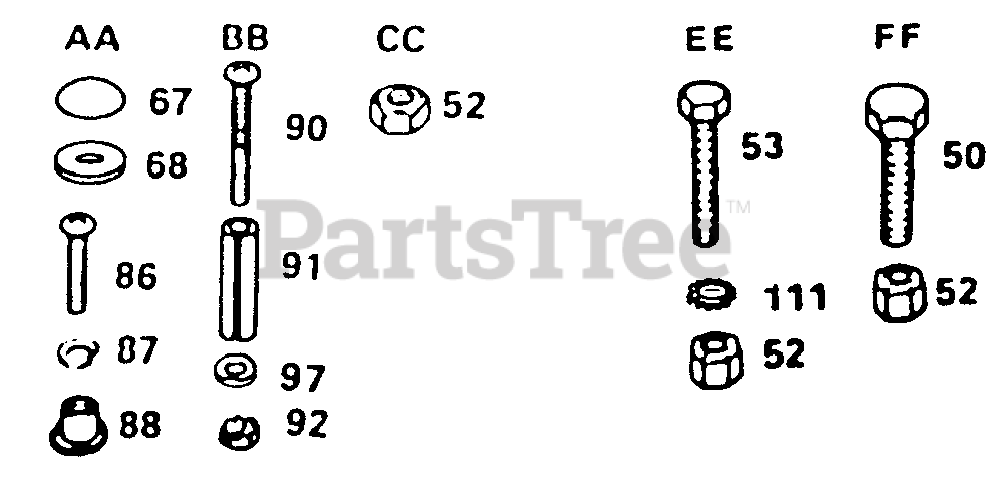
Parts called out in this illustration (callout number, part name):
50	Bolt, Hex 3/8 - 16 x 3/4
52	Nut, Crownlock 3/8 - 16
53	Bolt, Hex 3/8 - 16 x 1
67	Cap, Snap. Black
68	Washer, Cap, Snap
86	Screw, Cross Recess Pan Hd.Machine 10-24 x 1/2
87	Washer, Lock, No. 10
88	Nut, Weld
90	Screw, Machine Cross Recess 10 - 24 x 1-1 /4
91	Spacer, Split 10 x 3/4
92	Nut, Keps 10-24
97	Washer, 7/32 x 1/2 x 18 Ga.
111	Lockwasher, 3/8 Ext. Tooth
